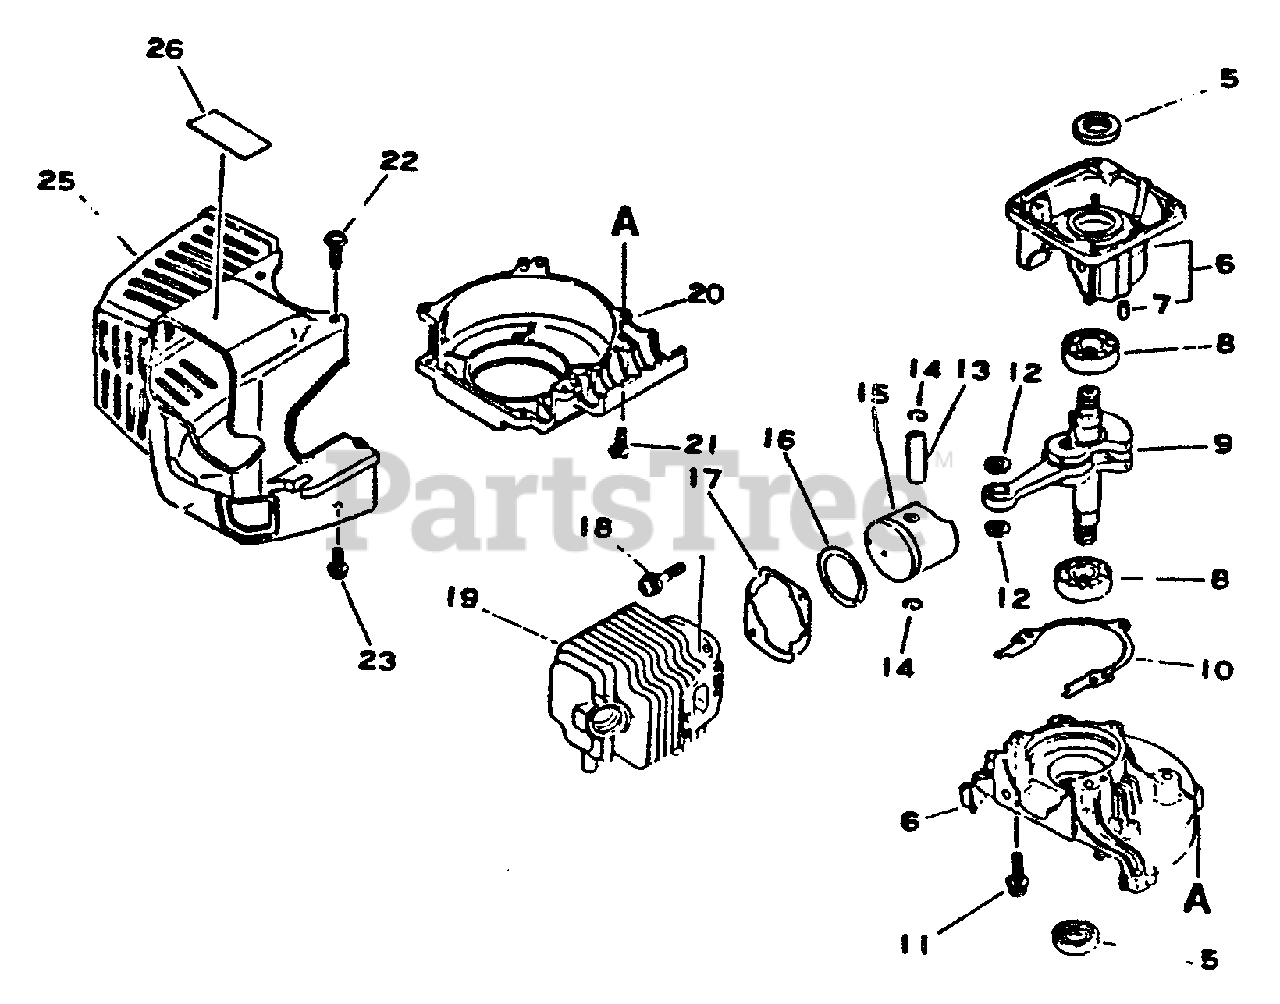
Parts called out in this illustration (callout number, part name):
5	SEAL, OIL 12
6	CRANKCASE KIT
7	PIN, LOCATING 4
8	BEARING, BALL - 6201 C3
9	CRANKSHAFT ASSY
10	GASKET, CRANKCASE
11	SCREW 5×28
12	WASHER, THRUST
13	PIN, PISTON 8
14	RING, SNAP
15	PISTON
16	RING, PISTON
17	GASKET, CYLINDER
18	BOLT 5×22
19	CYLINDER
20	COVER, FAN
21	SCREW 4×14
22	SCREW 4×12
23	SCREW 4×16
25	COVER, ENGINE - ORANGE
26	LABEL
